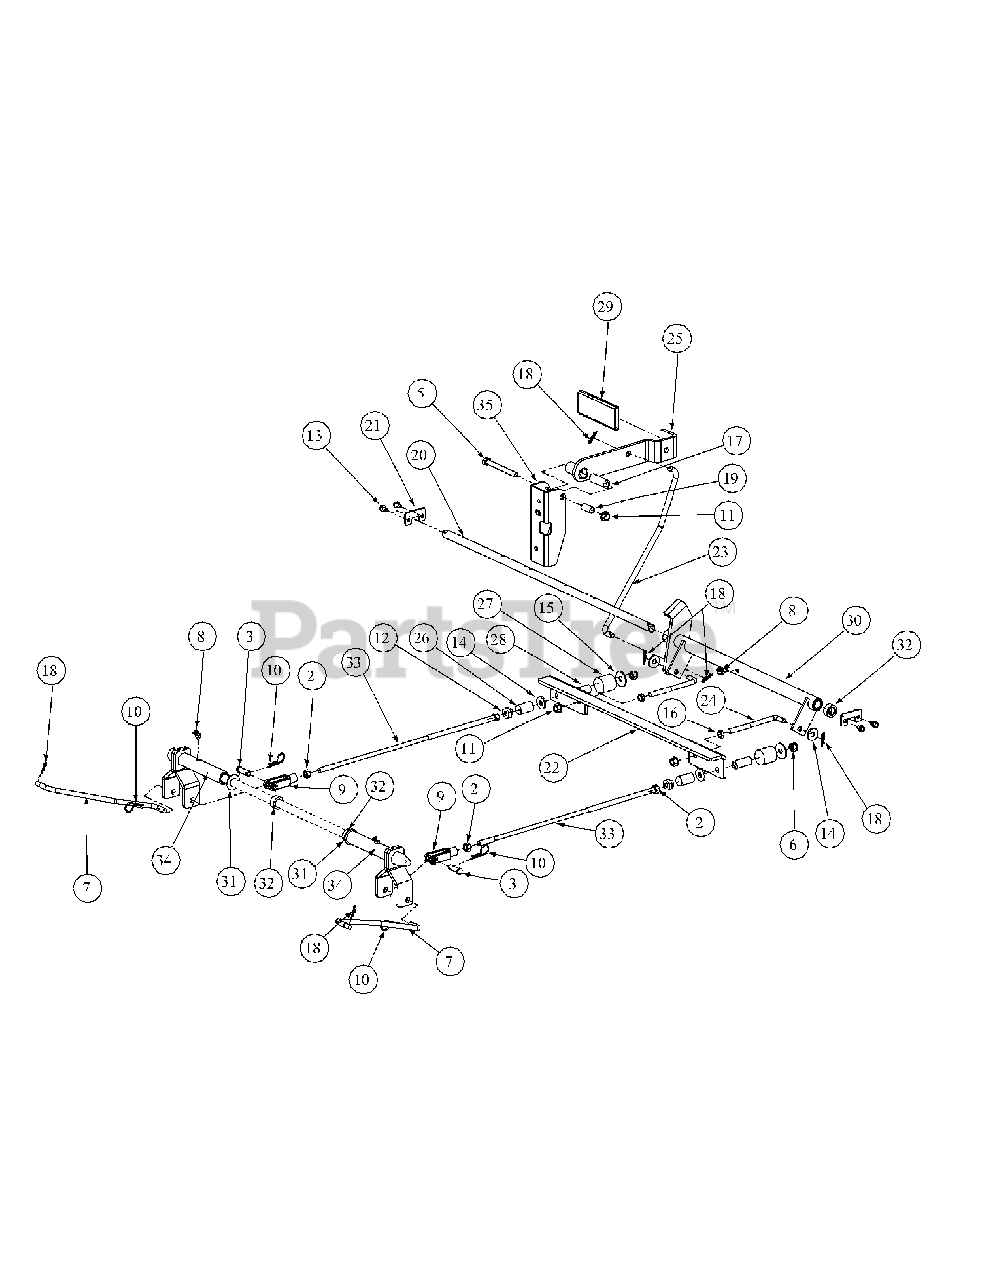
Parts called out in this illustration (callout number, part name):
2	Hex Nut, 3/8-16
3	Clevis Pin, 3/8 x 1-1/8
5	Hex Cap Screw, 3/8-16 x 3-1/2 OR
5	Hex Cap Screw, 3/8-16 x 3-1/4
6	Nylock Nut, 3/8-16
7	Rear Brake Linkage Rod
8	Grease Fitting, 1/4 -28, 90 degree
9	Yoke, 3/8-16
10	Hair Pin, 3/8" - 1/2"
11	Flange Lock Hex Nut, 3/8-16
12	Shoulder Nut
13	Screw, 1/4-20 x 1-1/2
14	Flat Washer, .406 ID x 1.0 OD x .105
15	Flat Washer, .411 x 1.25 x .100
16	Jam Nut, 3/8-16
17	Spacer, .375 x .50 x 1.75
18	Cotter Pin, .072 x 1.12 Lg
19	Spacer, .375 x .50 x 1.02 Lg
20	Bellecrank Mounting Shaft
21	Parking Brake Shaft Holder
22	Brake Bracket
23	Brake Rod
24	Connector Rod, 3/8 OD x 5.75
25	Brake Handle
26	Neutral Brake Spring
27	Force Brake Spring
28	Center Brake Hose
29	Parking Brake Grip
30	Brake Bearing Hub
31	Flat Washer, 5/8
32	Shaft Collar, .625 ID x 1" OD x .438
33	Connector Rod, 3/8 OD x 17.88 Lg
34	Rear Brake Arm Assembly
35	Parking Brake Mounting Bracket
